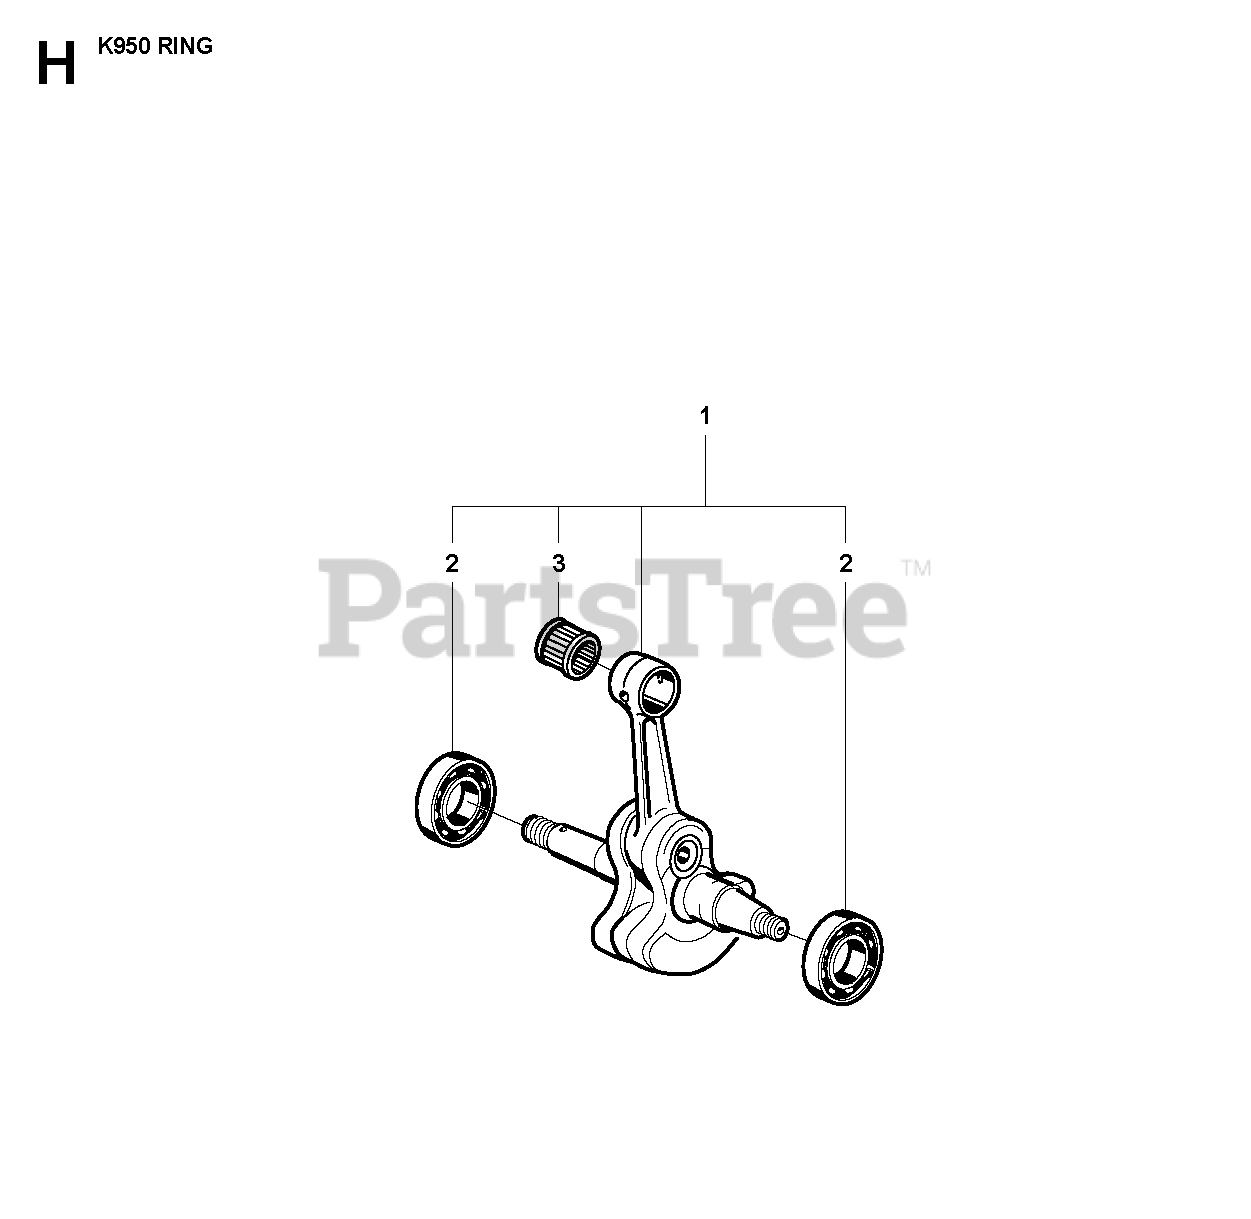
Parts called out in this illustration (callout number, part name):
1	CRANKSHAFT ASSYIncl. 2, 3
2	BALL BEARING
3	NEEDLE BEARING
